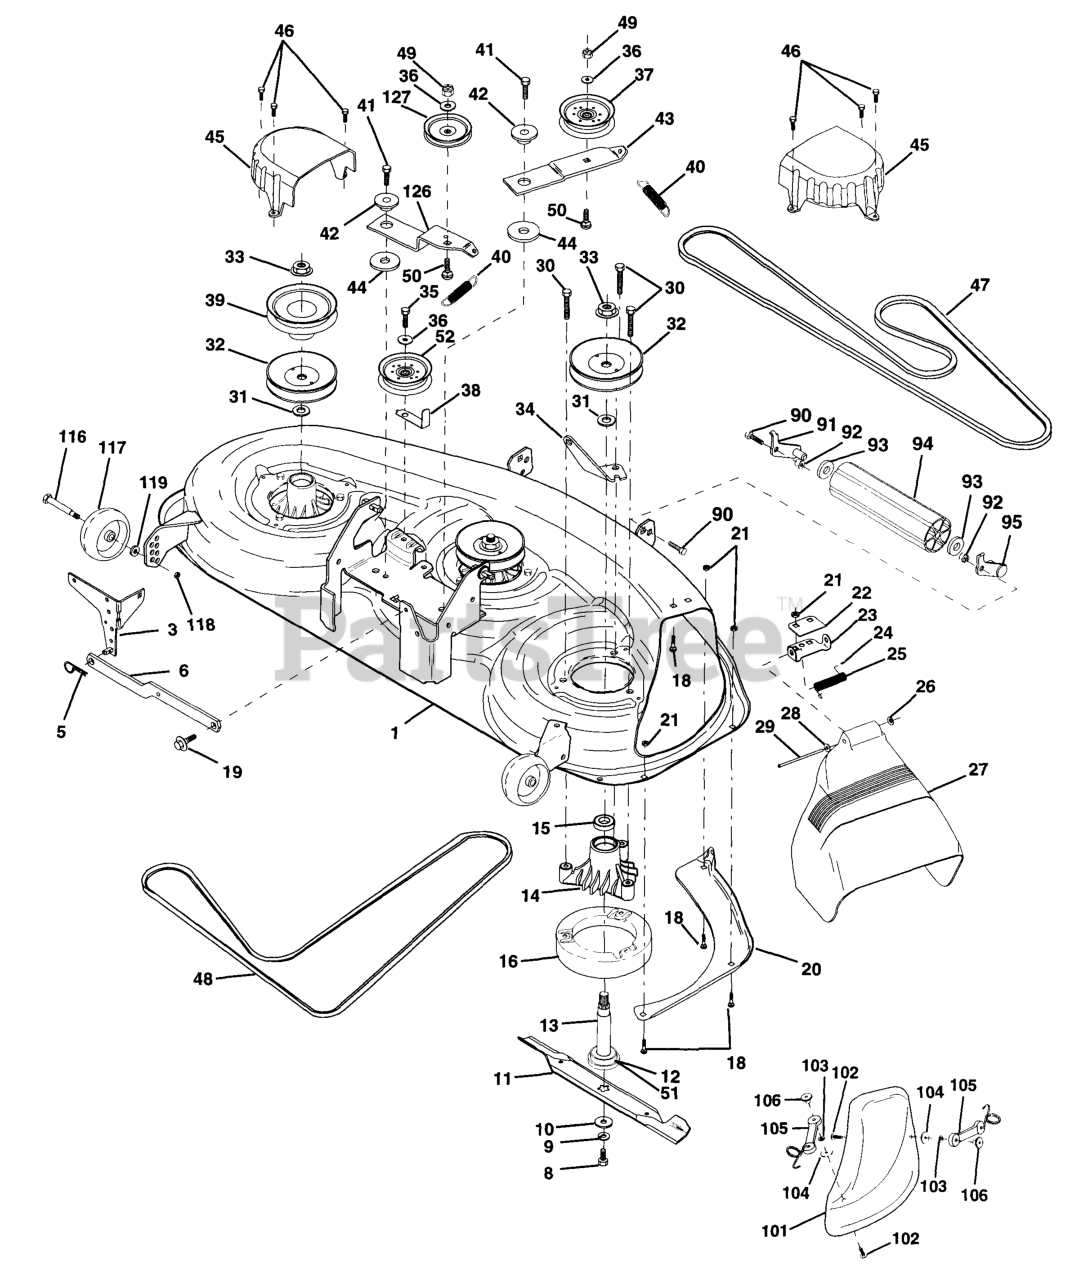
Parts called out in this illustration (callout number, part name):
1	HOUSING MOWER
3	BRACKET SWAY BAR
5	RETAINER-SPRNG RB
6	REAR SUSP ARM
8	BLADE BOLT
9	LOCKWASHER
10	WASHER.BLADE
11	MULCH BLADE 46"
12	BEARING.BALL.#6204.(MANDREL)
13	SHAFT.ASM.W/BEARING
14	HOUSING.MANDREL.44/46" VENT
16	STRIPPER
18	BOLT
19	BOLT SHD 5/16-18
20	BAFFLE, VORTEX MOWER 46"
21	LOCKNUT
22	STIFFENER BRACKET
23	DEFLECTOR BRACKET
24	CAP-SLEEVE LT
25	SPRING TORSION
26	NUT PUSH M
27	SHIELD, DEFLECTOR MOWER
28	Washer 11/32 x 5/8 x 16 Ga.
29	ROD.HINGE
30	SCREW
31	WASHER
32	PULLEY, MANDREL
33	NUT
34	ANCHOR, SPRING DECK 46"
35	SCREW LT
36	WASHER
37	FLAT IDLER PULLEY
38	KEEPER
39	PULLEY.DRIVEN.DECK.46"
40	SPRING.SEC.44"VEN
41	SCREW
42	SPACER RETAINER
43	ARM IDLER DECK 46"
44	HARDENED WASHER
45	COVER MANDREL 46
46	SCREW.1/4-20X5/8
47	BELT V SECONDARY
48	V-BELT PRIMARY 50"
50	BOLT.3/8-16X1.50
51	WASHER FELT
52	PULLEY IDLER FLAT 46 PRI DRIVE
90	BOLT
91	BRACKET LH (A)
92	NUT
93	Washer 17/32 x 7/8 x 16 Ga.
94	NOSE ROLLER
95	BRACKET RH (B)
101	COVER.MULCH.46"3-BLADE.(2 2)
102	SCREW
103	LOCKWASHER #10
105	LATCH ASSEMBLY
106	WELDNUT
116	BOLT, SHOULDER
117	WHEEL GAGE DONUT
118	LOCKNUT
119	WASHER.5/16.FLAT.STE.STD.
126	ARM IDLER PRIM 46
127	PULLEY.IDLER.4.25
